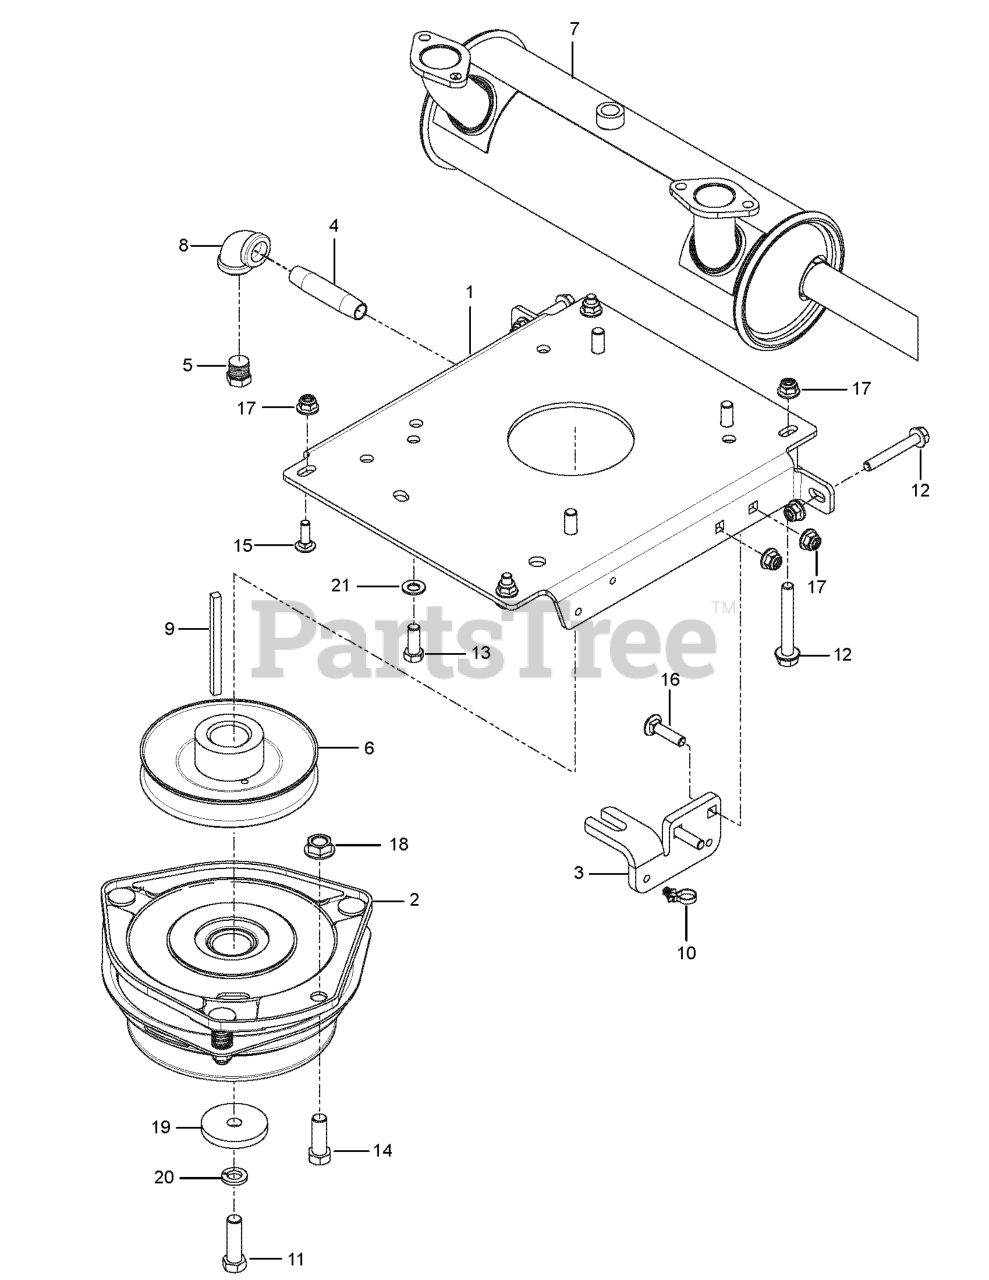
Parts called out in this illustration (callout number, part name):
1	PLATE.PNT.ENGINE.PZ/PZT.EDIP
2	CLUTCH, GT3.5
3	STOP, CLUTCH, OGURA
4	PIPE NIPPLE 3/8 X 3
5	PLUG, DRAIN 3/8 NPTF
6	PULLEY, ENGINE
7	MUFFLER.KOH.EFI.824CC
7	MUFFLER YAMAHA PN: 7UD-E4711-
8	90 DEG.ELBOW 3/8NPT
9	KEY, 1/4 SQ X 3.5
10	TIE WRAP, 8-3/8", W/CLIP
11	CLUTCH BOLT7/16-20X1.5GR5.96HR
12	HHFS 5/16-18 X 2.25 GD 5
13	HCS 3/8-16X1.GRD.5.ZD
14	BOLT FIN HEX 7/16-14 X 1
15	RHSNB 5/16C X 1
16	RHSNB 5/16-18 X 1-1/2 GR 5 ZD
17	5/16-18 NYLOC FLANGE NUT
18	NUT 7/16C WHIZ
19	BLADE WASHER
20	WASHER 7/16 LOCK
21	WASHER, 3/8 DISC SPRING SPEC
